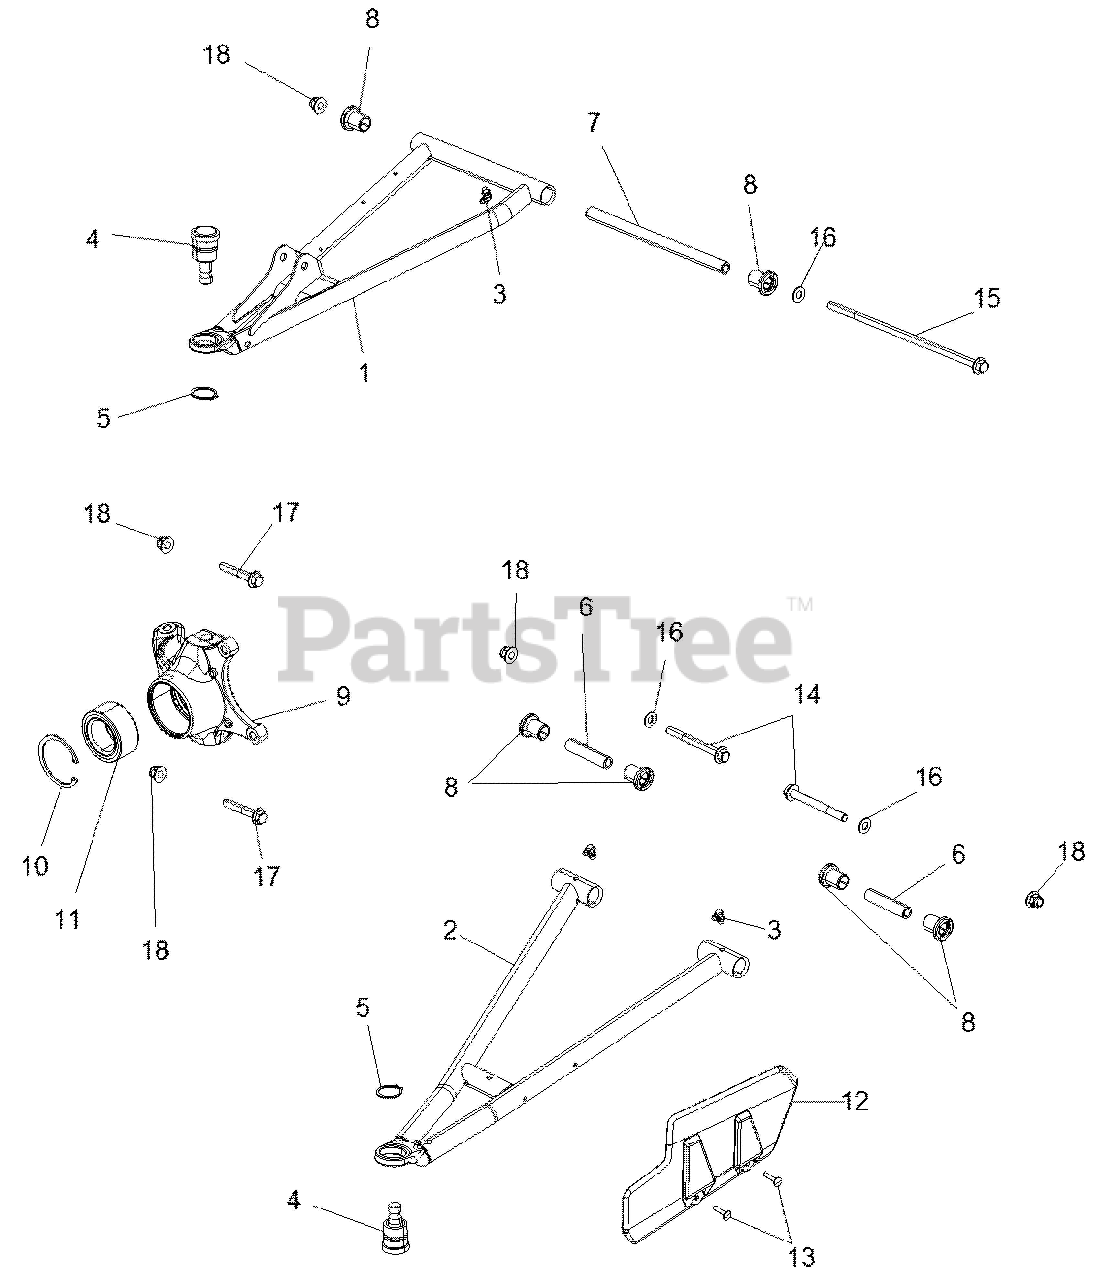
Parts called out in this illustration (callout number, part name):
1	WELD-A-ARM,FR,UPR,LH,BLK
1	WELD-A-ARM,FR,UPR,RH,BLK
2	WELD-A-ARM,FR,LWR,LH,M.BLK
2	WELD-A-ARM,FR,LWR,RH,M.BLK
3	FITTING, ZERK,90 DEGREE
4	BALL-JOINT,10MM STUD
5	RING-RETAINER,EXTERNAL,1.188
6	SHAFT-PIVOT,70.99MM,15.88OD
7	SHAFT-PIVOT,250.28MM,15.88OD
8	BUSHING-STANDARD,ORV
9	CARRIER-BEARING,FRONT,LH(MACH)
9	CARRIER-BEARING,FRONT,LH
9	CARRIER-BEARING,FRONT,RH(MACH)
9	CARRIER-BEARING,FRONT,RH
10	RING, RETAINING, INTERNAL
11	BEARING-BALL,SEALED,44X72X33.1
12	SHIELD-CV,FRONT,LH,BLK
12	SHIELD-CV,FRONT,RH,BLK
13	RIVET(50) *
14	SCR-HXFL-M10X1.25X95 10.9 ZOD
15	SCR-HXFL-M10X1.25X275 10.9 ZOD
16	WASHER,3/8 FW
17	SCR-HXFL-M10X1.25X60 10.9 ZOD
18	NUT-M10X1.25,FLG,NYLOC-OLIVE D
